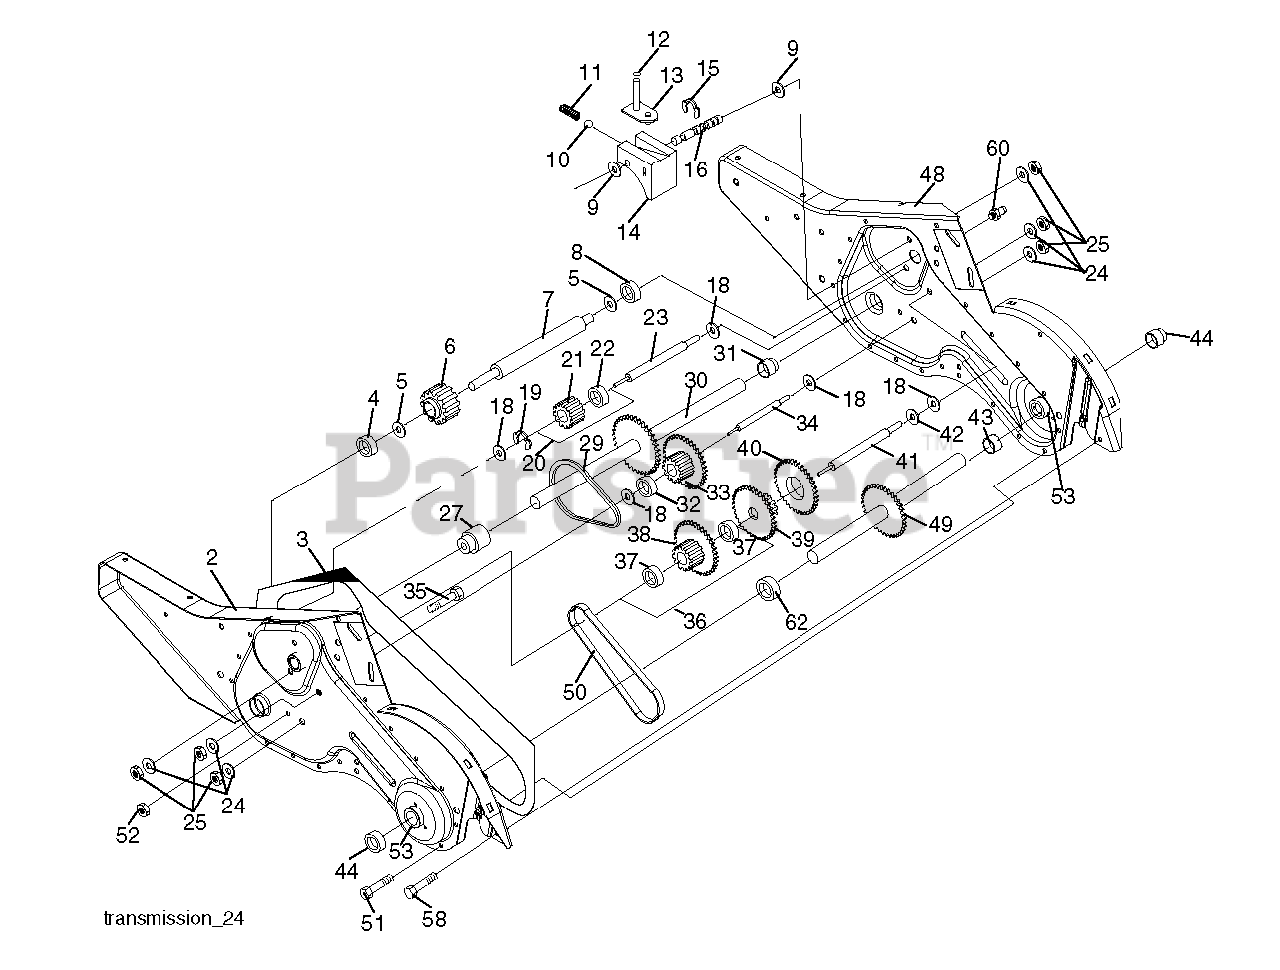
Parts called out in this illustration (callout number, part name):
2	GEARCASE.ASM.CRT.LH.W/BEARING
3	GASKET.GEARCASE.CRT/DRT.TILLER
4	NEEDLE BRNG LT
5	THRUST WASHER
6	GEAR.PINION.INPUT
7	SHAFT.INPUT."D".TILLER
8	BEARING TI
9	WASHER, SEAL (2 2)
10	STEEL BALL KIT
11	SPRING-SHIFT CRT
13	BRACKET ASM.SHIFT.CRT
14	SHIFT FORK TI
16	SHAFT.SHIFTER.TILLER
20	GEAR ASSY CRT
21	GEAR-REV IDLR CRT
22	NEEDLE BEARING TI
24	LOCKWASHER
25	NUT.ASF.HEX.7/16
27	BEARING.GROUND.DRIVE
30	GROUND SHAFT ASS'Y
31	BEARING, SHAFT RH CRT
33	SPRCKT 8 GEAR CRT
34	SHAFT.SECONDARY.REDUCTION.CRT
35	SCRW WHIZ LOK CRT
36	SPROCKET.ASM.W/BEARING.TILLER
37	BEARING
38	SPROCKET, TINE
41	SHAFT.REDUCTION.TILLER
42	BRNG RACE T
44	SEAL ASM, OIL
48	GEARCASE.ASM.CRT.RH.W/BEARING
49	SHAFT.ASM.TINE
50	CHAIN.TILLER
51	SCREW
53	BEARING KIT
58	BOLT SHOULDER 1/4-20 UNC X.875
60	FITTING.GREASE.TAPERED
62	SPACER.1.015X1.50X.650
